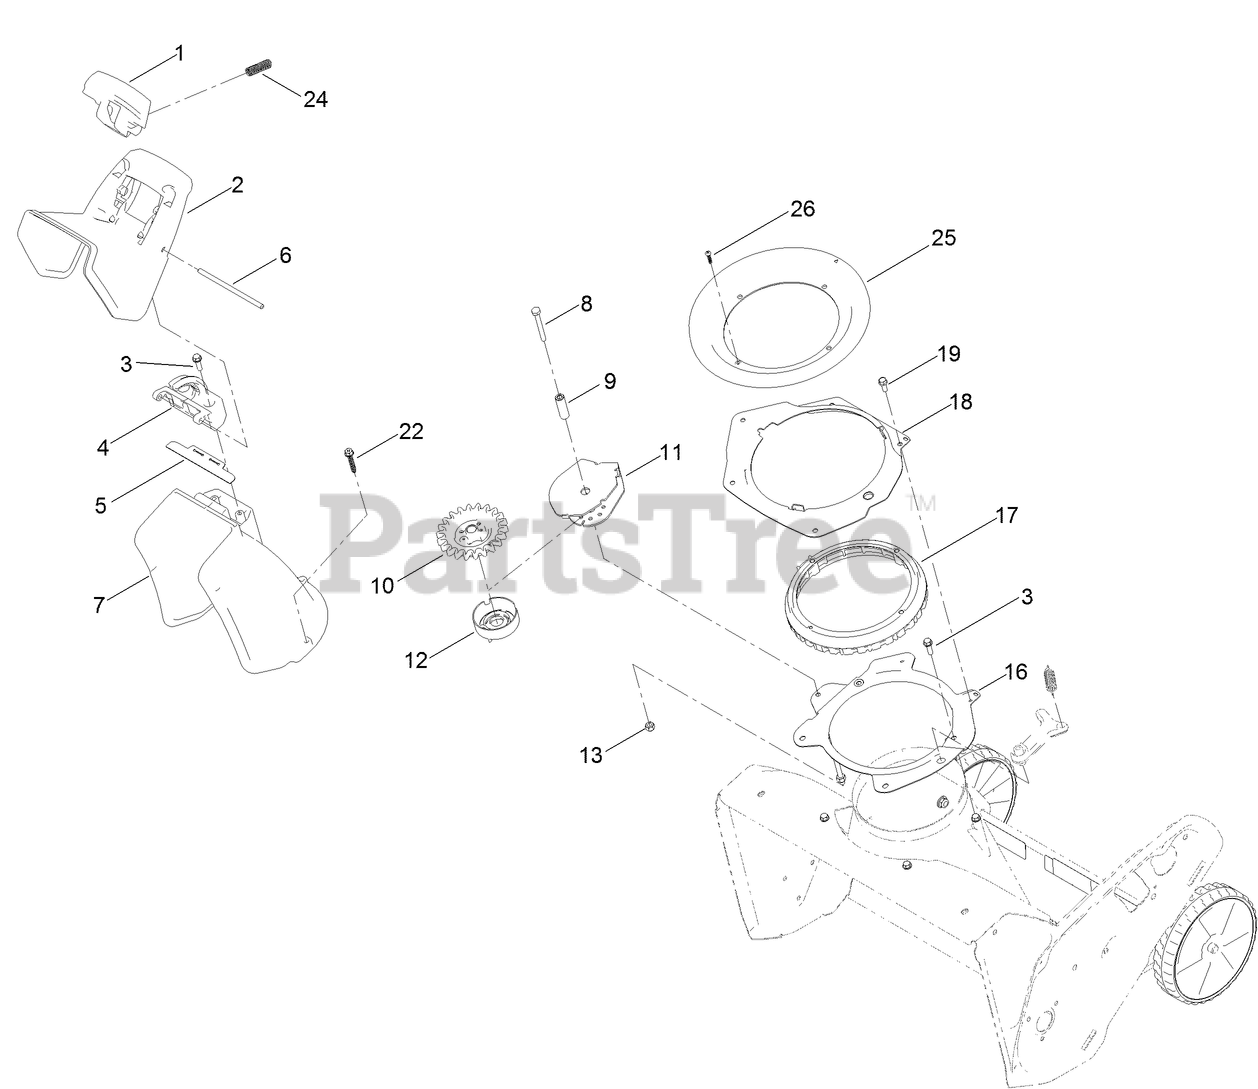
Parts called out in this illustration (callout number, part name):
1	TRIGGER-DEFLECTOR
2	DEFLECTOR-CHUTE, CE
3	SCREW-HWH
4	HINGE-RATCHET, DEFLECTOR
5	SEAL-DEFLECTOR
6	HINGE PIN-DEFLECTOR
8	SCREW-HH
9	SPACER-SLEEVE, PINION
10	PINION-GEAR
11	BRACKET-PINION
12	RETAINER-CABLE
13	NUT-LOCK, NI
16	RING-SUPPORT, CHUTE
17	RING-CHUTE, GEAR
18	RETAINER-RING, CHUTE
19	SCREW-HWH
22	SCREW-PLASTITE
24	SPRING-COMPRESSION
25	SEAL-RING, CHUTE
26	SCREW-PPH
